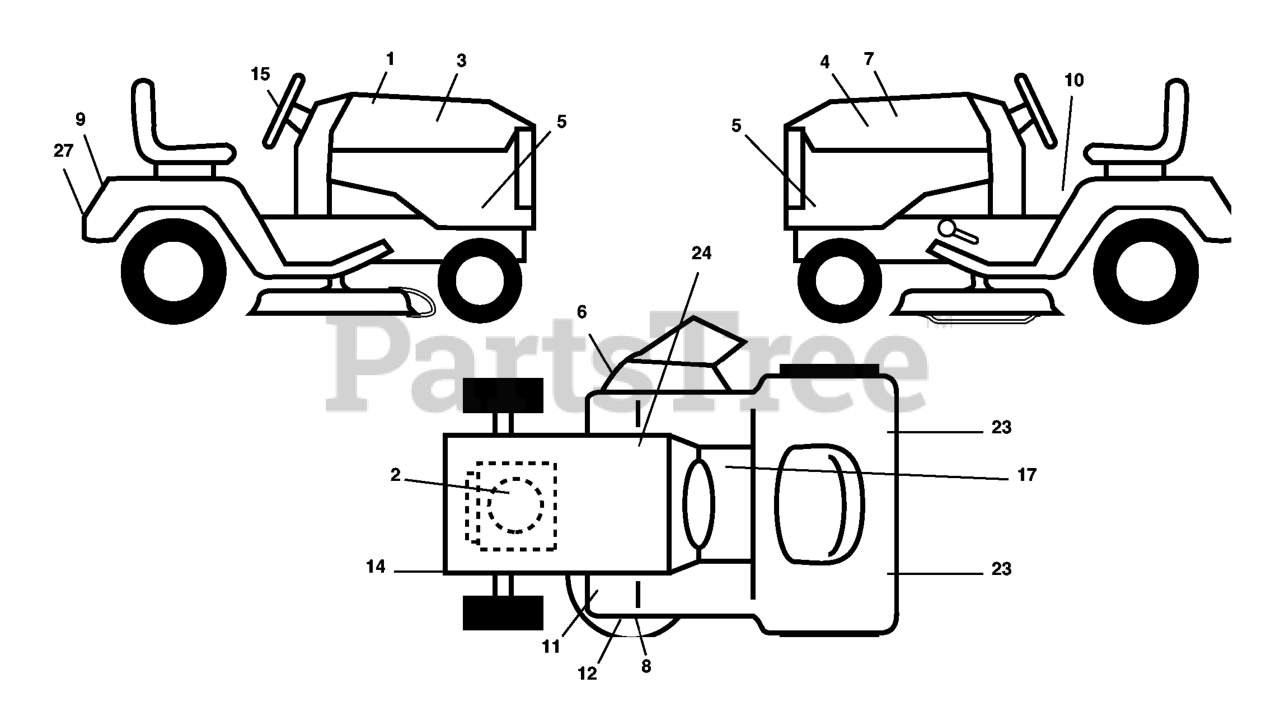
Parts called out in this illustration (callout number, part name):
1	WARNING DECAL
2	DECAL, ENGINE
3	HOOD DECAL LH
4	DECAL, HOOD LH
5	DECAL HOOD SIDES
6	DECAL.WARN.KEEP.HAND.AWAY
7	DECAL HOOD CUST. RESP.
8	DECAL, MOWER HEAVY DUTY
9	DECAL, FENDER
10	DECAL FENDER DANGER
11	DECAL, FOOTREST
12	DECAL CLUTCH/BRAKE
14	DECAL V-BELT SCHEMATIC
15	DECAL.WHEEL.STEERING.HUSQ.PERM
17	DECAL, SADDLE BRAKE PARKING
23	REFLECTOR-TAIL YT
24	DECAL BTRY SYMBOLS
27	DECAL.BYPASS.FENDER.CRD.LT.YT
